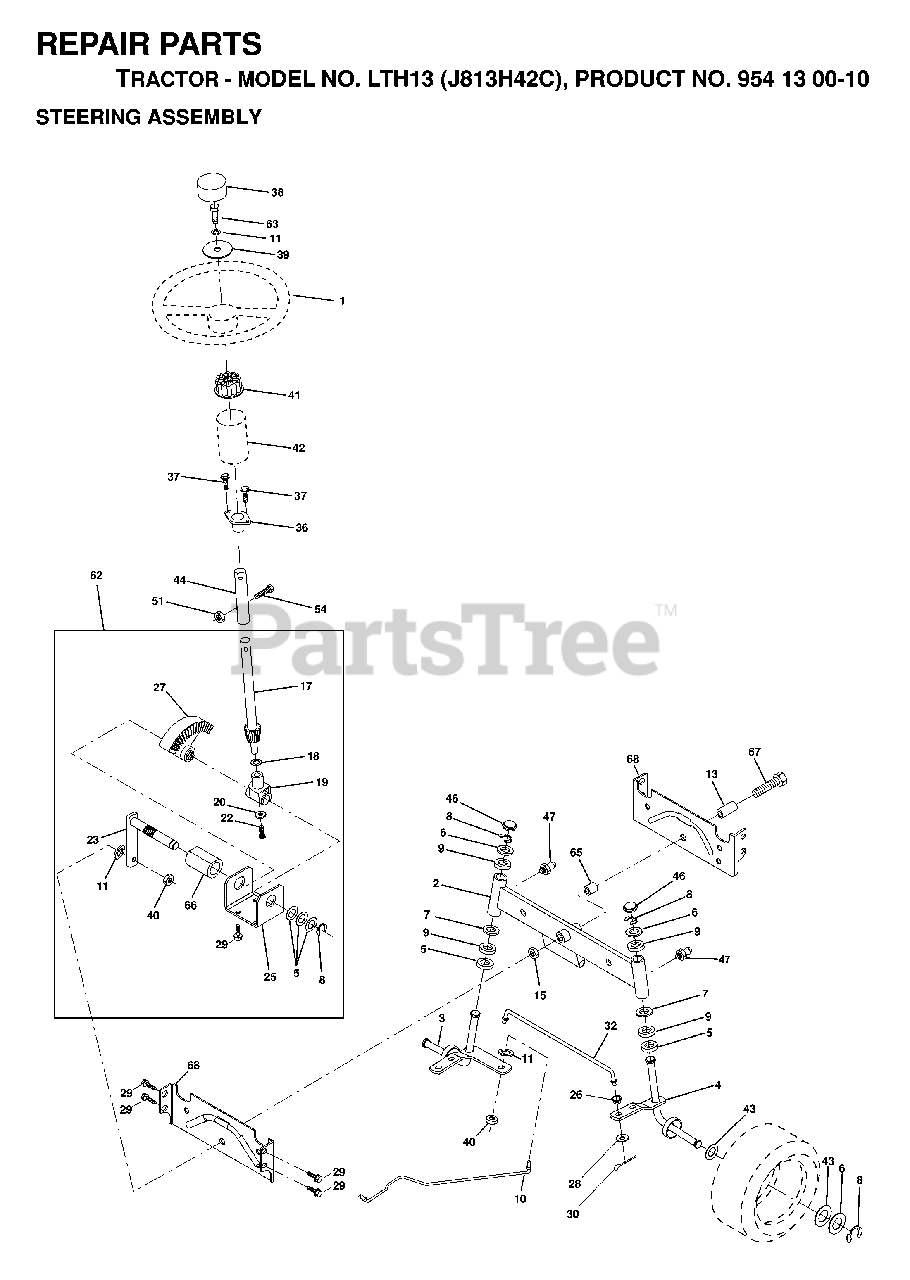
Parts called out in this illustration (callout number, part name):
2	AXLE ASSY
3	SPINDLE ASM LH
4	SPINDLE ASM RH
8	RING CLIP
9	BRNG T
10	DRAGLINK-STAMPED
11	WASHER, LOCK 3/8
13	BEARING AXLE
15	NUT-LOC,FLANGE LT
17	SHAFT ASM STEERING
18	THRUST WASHER
19	SHAFT,SUPPORT
20	WASHER
22	SCREW HEX SOCKET 1/4-20 X 5/8
23	SHAFT PITMAN
25	BRACKET STEERING
26	BUSHING.DRAGLINK
27	GEAR.SECTOR
28	WASHER
29	SCREW
30	COTTER PIN
32	TIE ROD
36	BUSHING, STEERING
38	RP INSERT
39	WASHER T
40	GRIPCO NUT
41	ADAPTER LT
42	STEERING BOOT, GRAY
44	EXT SHAFT STEERING
46	CAP.SPINDLE
47	ZERK M
51	NUT.71038.31-18.HEX.NYLOCK
54	BOLT.5/16-18X1-1/4 FULL.THREAD
62	KIT, STEERING ASSEMBLY
65	SPACER AXLE
66	BEARING ARM
67	BOLT.HEX.FINISHED.5/8
68	AXLE, BRACE
